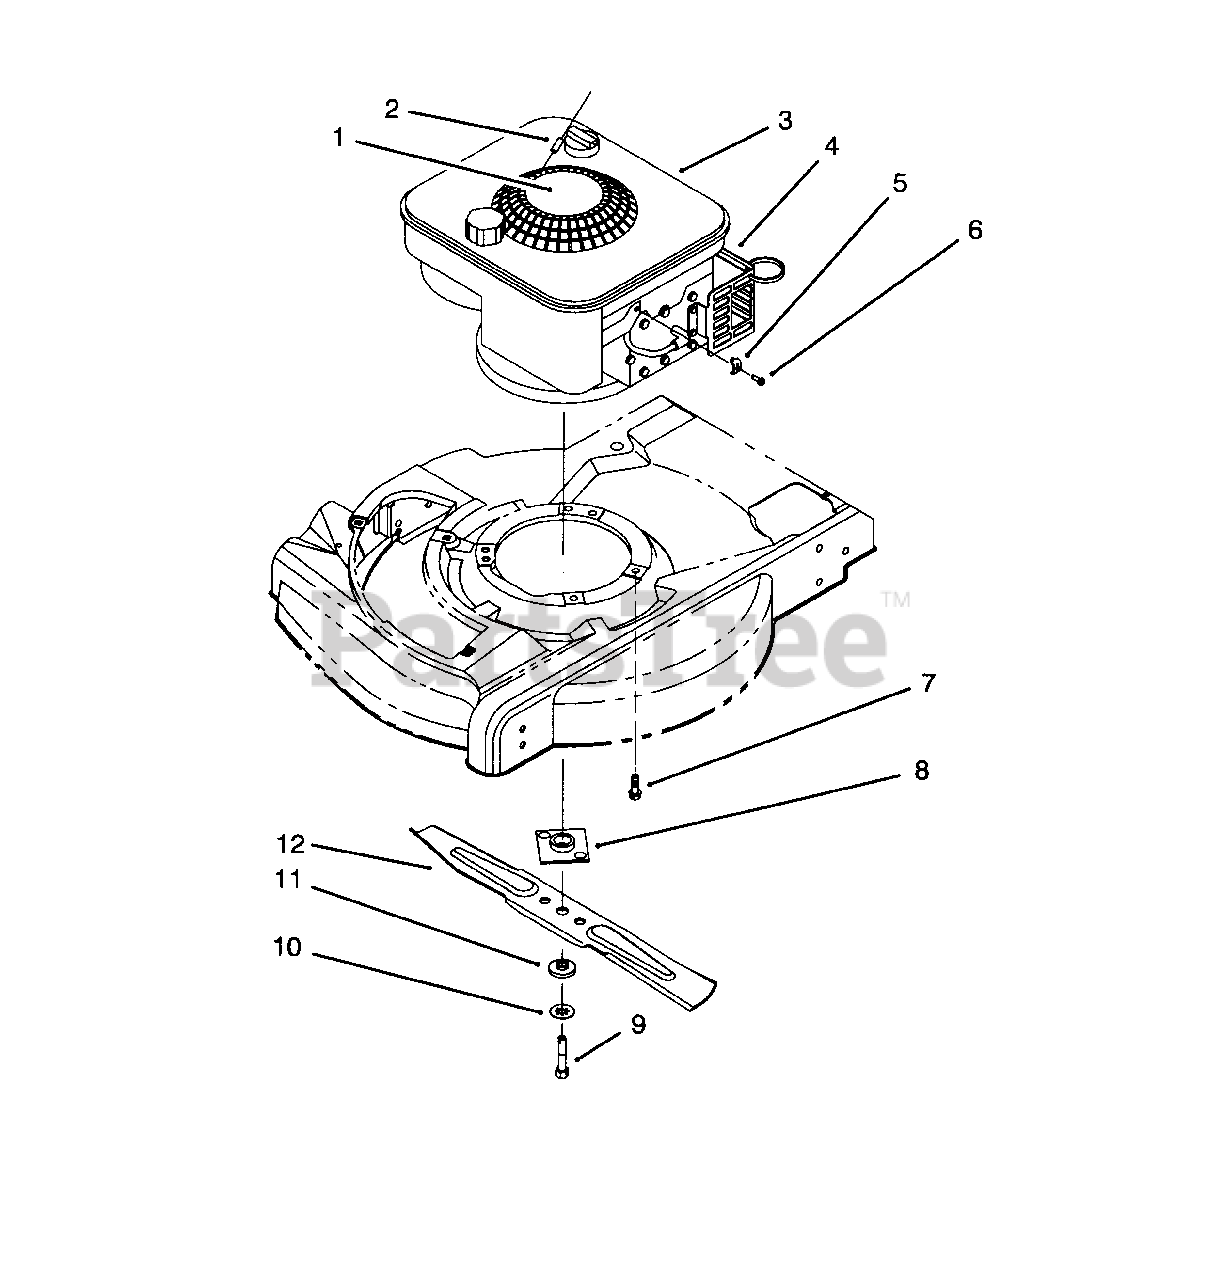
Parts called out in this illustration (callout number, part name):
1	Decal-Shroud
2	Stop-Rope
3	Engine
4	Shield-Muffler
5	Clamp-Casing
6	Screw-Clamp
7	Screw-Engine
8	Collar & Plate
9	Bolt-Blade
10	Washer-Lock
11	Spacer-Blade
12	Blade
